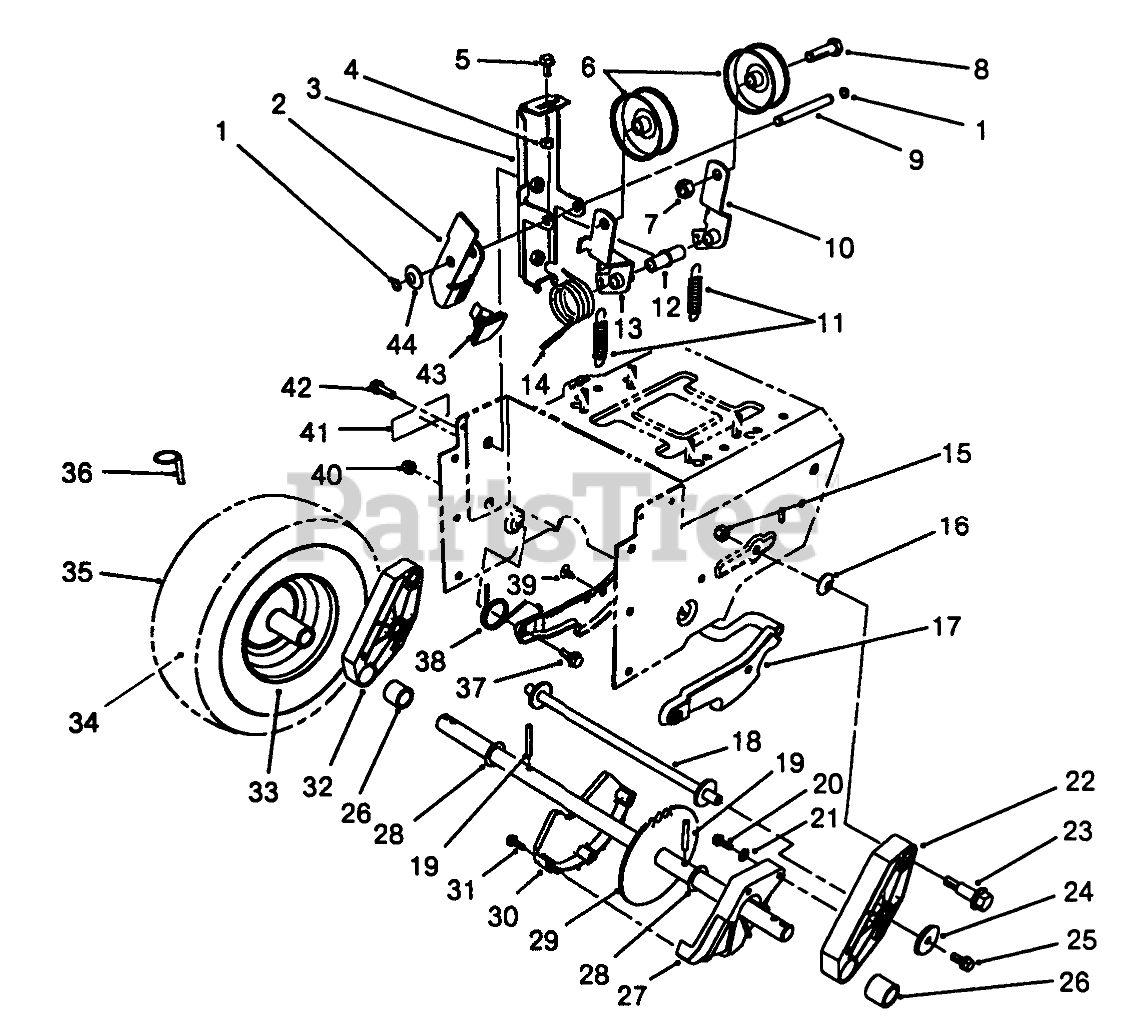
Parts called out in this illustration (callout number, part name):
1	Ring-Retaining
2	ARM-BRAKE
3	IDLER ARM BRACKET ASM
4	NUT-LOCK, NI
5	SCREW-HHF
6	PULLEY-IDLER
7	NUT-LOCK, NI
8	SCREW-HH
9	PIN-IDLER
10	ARM-IDLER, TRACTION
11	SPRING-EXTENSION
12	BUSHING-IDLER
13	ARM-IDLER, IMPELLER
14	SPRING-TORSION
15	NUT-LOCK, NI
16	WASHER-SPRING
17	Latch-Arm
18	PIVOT TUBE WA
19	PIN-ROLL, SLOTTED
20	Screw-Hex Flange Hd.
21	WASHER-FLAT
22	Pivot Arm Assembly L.H. (Incl. Ref. #26)
23	BOLT-SHOULDER
24	WASHER
25	SCREW-TAPTITE
26	BUSHING-AXLE
27	GUARD-CHAIN, LH
28	WASHER-THRUST
29	AXLE WA (24")
30	GUARD-CHAIN, RH
31	SCREW-PPH
32	Pivot Arm Assembly R.H. (Incl. Ref. #26)
33	Wheel
34	TUBE-INNER
36	PIN-LYNCH
37	SCREW-SHOULDER
38	SPRING-LATCH, TORSION
39	FASTENER-PANEL
40	NUT-LOCK, NI
41	Decal-Warning
42	SCREW-HHF
43	Brake Pad
44	WASHER-CURVED
